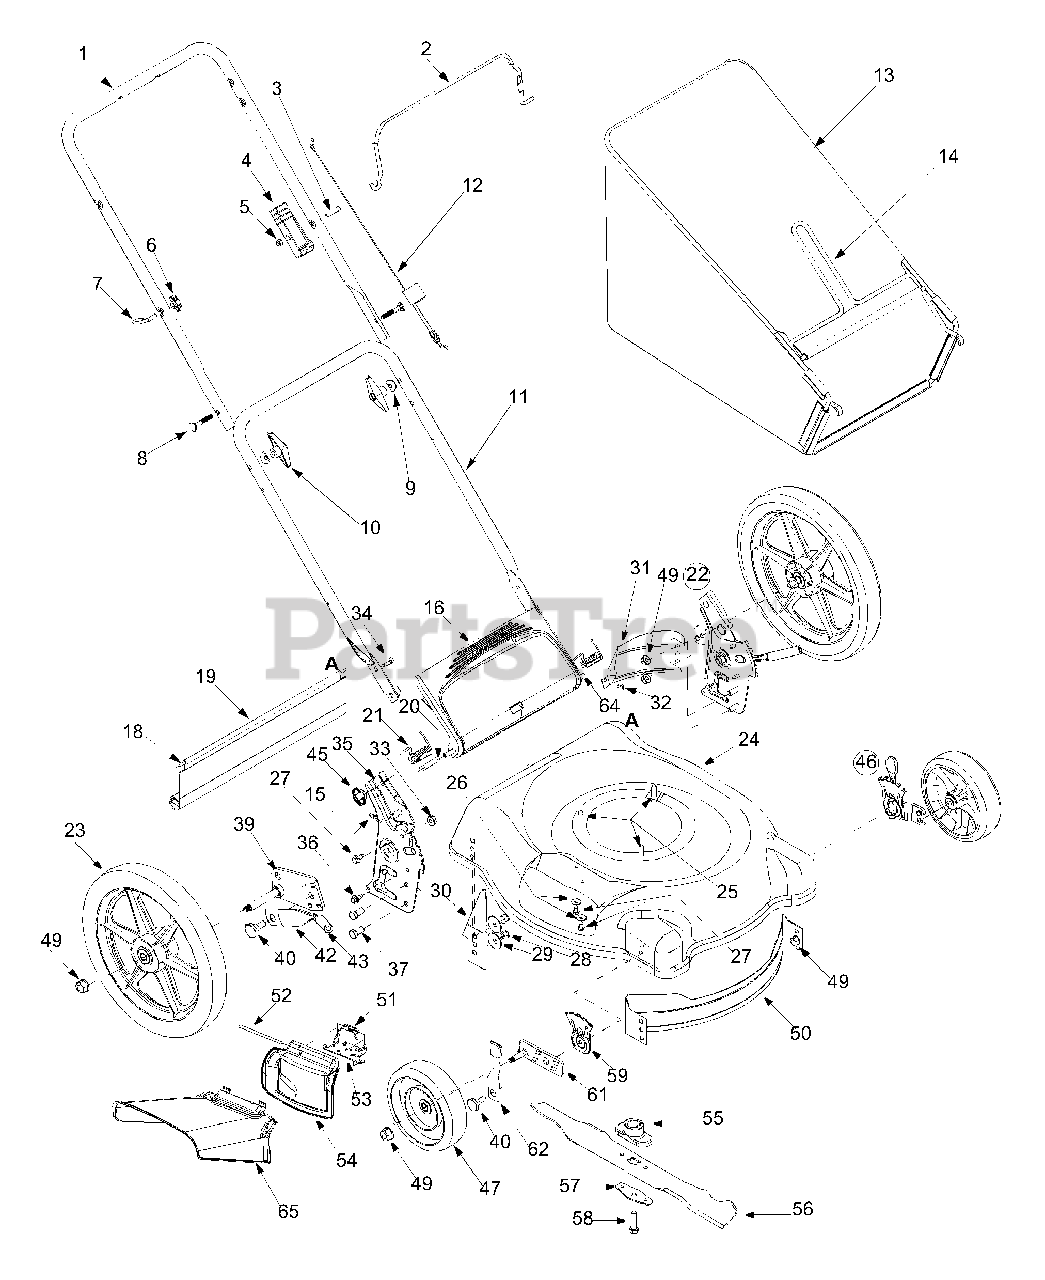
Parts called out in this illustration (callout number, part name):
3	C-Sunk Screw 1/4-20 x 1.3"
4	Throttle Housing
5	Hex Lock Nut 1/4-20
6	Handle Knob
7	Rope Guide
8	Carriage Bolt 5/16-18 x 2"
9	Shoulder Washer .320 ID x .930 OD
10	Wing Nut
12	Control Cable 37.25"
13	Grass Bag
15	Hairpin Clip
16	Grass Bag Door
17	Rear Mulch Plug
18	Wire Rod
19	Trailshield
20	Spacer .375 O.D. x .50 I.D. x 1.02"
21	Torsion Spring - RH
22	Handle Bracket Assembly - RH
23	Rear Wheel: 8-Spoke Bar Gray 12 x 2
26	Bell Washer .265 ID x .75 OD
28	Hex Lock Nut 3/8-16
29	Bell Washer .390 ID x .380 OD
32	Tap Screw 1/4-14 x .625.
33	Flange Lock Nut 3/8-16
34	Hex Carriage Screw 1/4-20
35	Handle Bracket Assembly - RH
36	TT Screw 1/4-14 x .625
37	Hex Screw 3/8-16 x 0.75
38	Hex Cap Screw 3/8-16 x 1.0
39	Pivot Bar Assembly - RH
40	Shoulder Screw
42	Spring Lever
43	Grip: Spring Lever
45	Wing Nut
46	Front Height Adjuster Assembly - RH
47	Front Wheel: 8-Spoke Bar Gray 8 x 2
49	Flange Lock Nut 3/8-16
52	Hinge Pin
54	Mulching Plug
55	Blade Adapter
56	Blade: 21" Mulching
57	Blade Bell Support
58	Hex Cap Screw 3/8-24 x 1.5
59	Height Adjustment Plate
60	Knob
61	Pivot Bar Assembly - RH
62	Spring Lever
64	Chute Door Pivot Rod
65	Side Discharge Deflector
